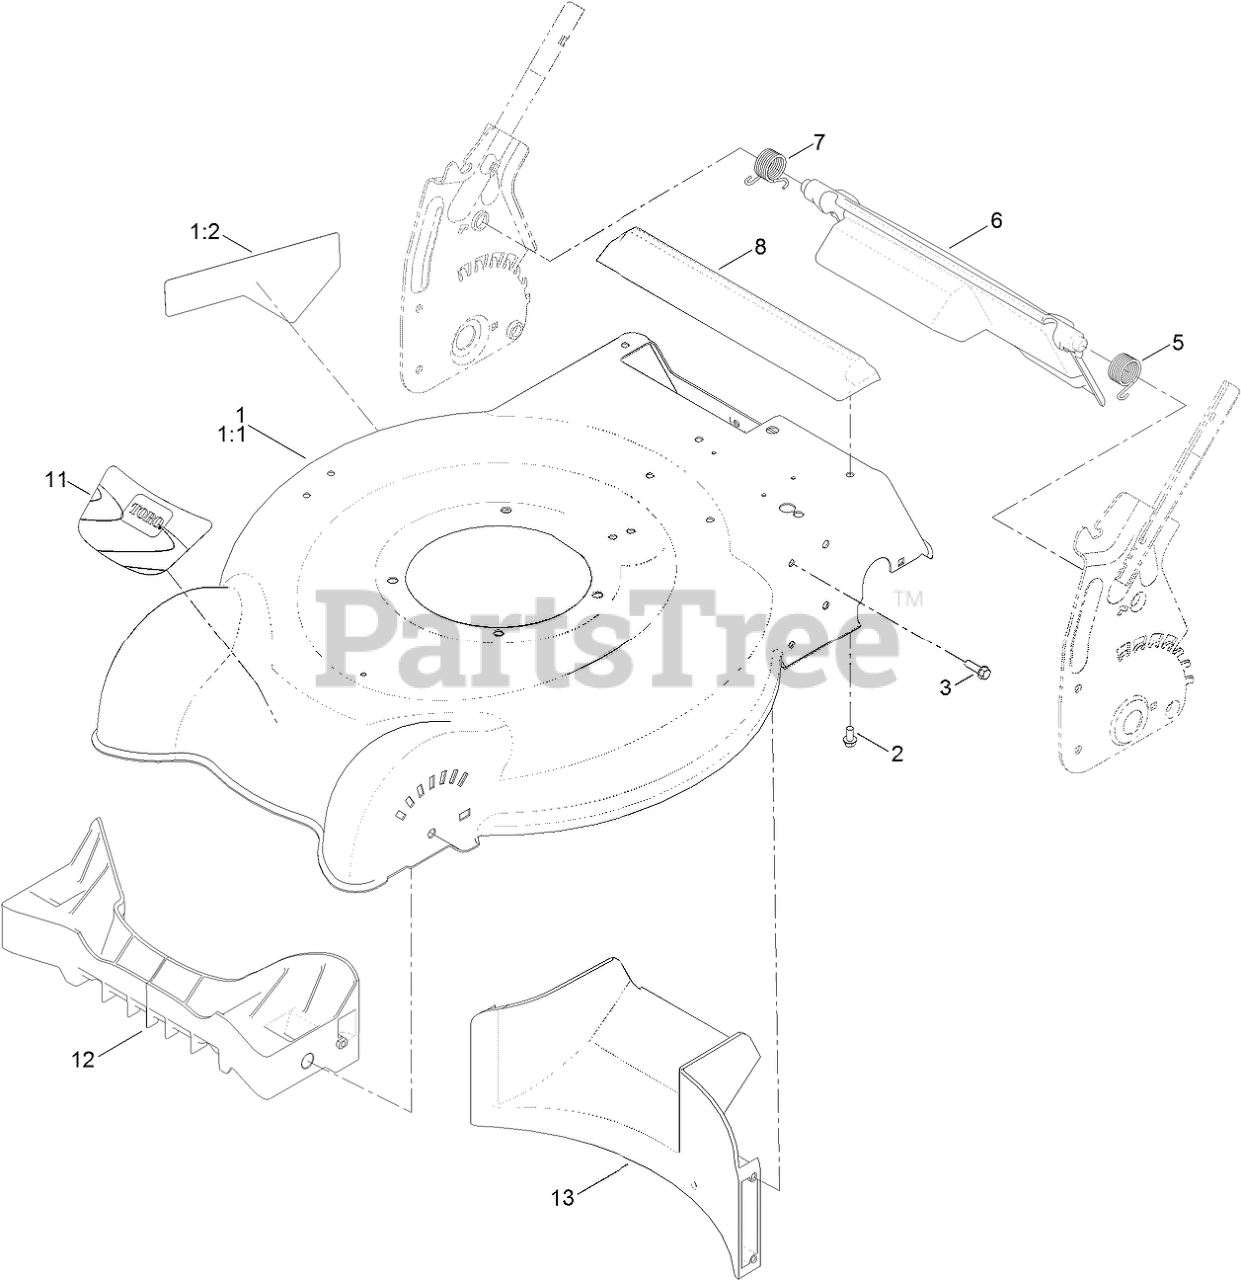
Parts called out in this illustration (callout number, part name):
1	ELECTRIC HOUSING ASM
1:1	DECK-20 INCH
1:2	DECAL-DANGER
2	SCREW-PLASTITE
3	SCREW-HWH
5	SPRING-TORSION, LH
6	DEFLECTOR-REAR
7	SPRING-TORSION, RH
8	CHUTE-REAR
11	DECAL-BATTERY
12	BAFFLE-THROW, FRONT
13	BAFFLE-REAR
